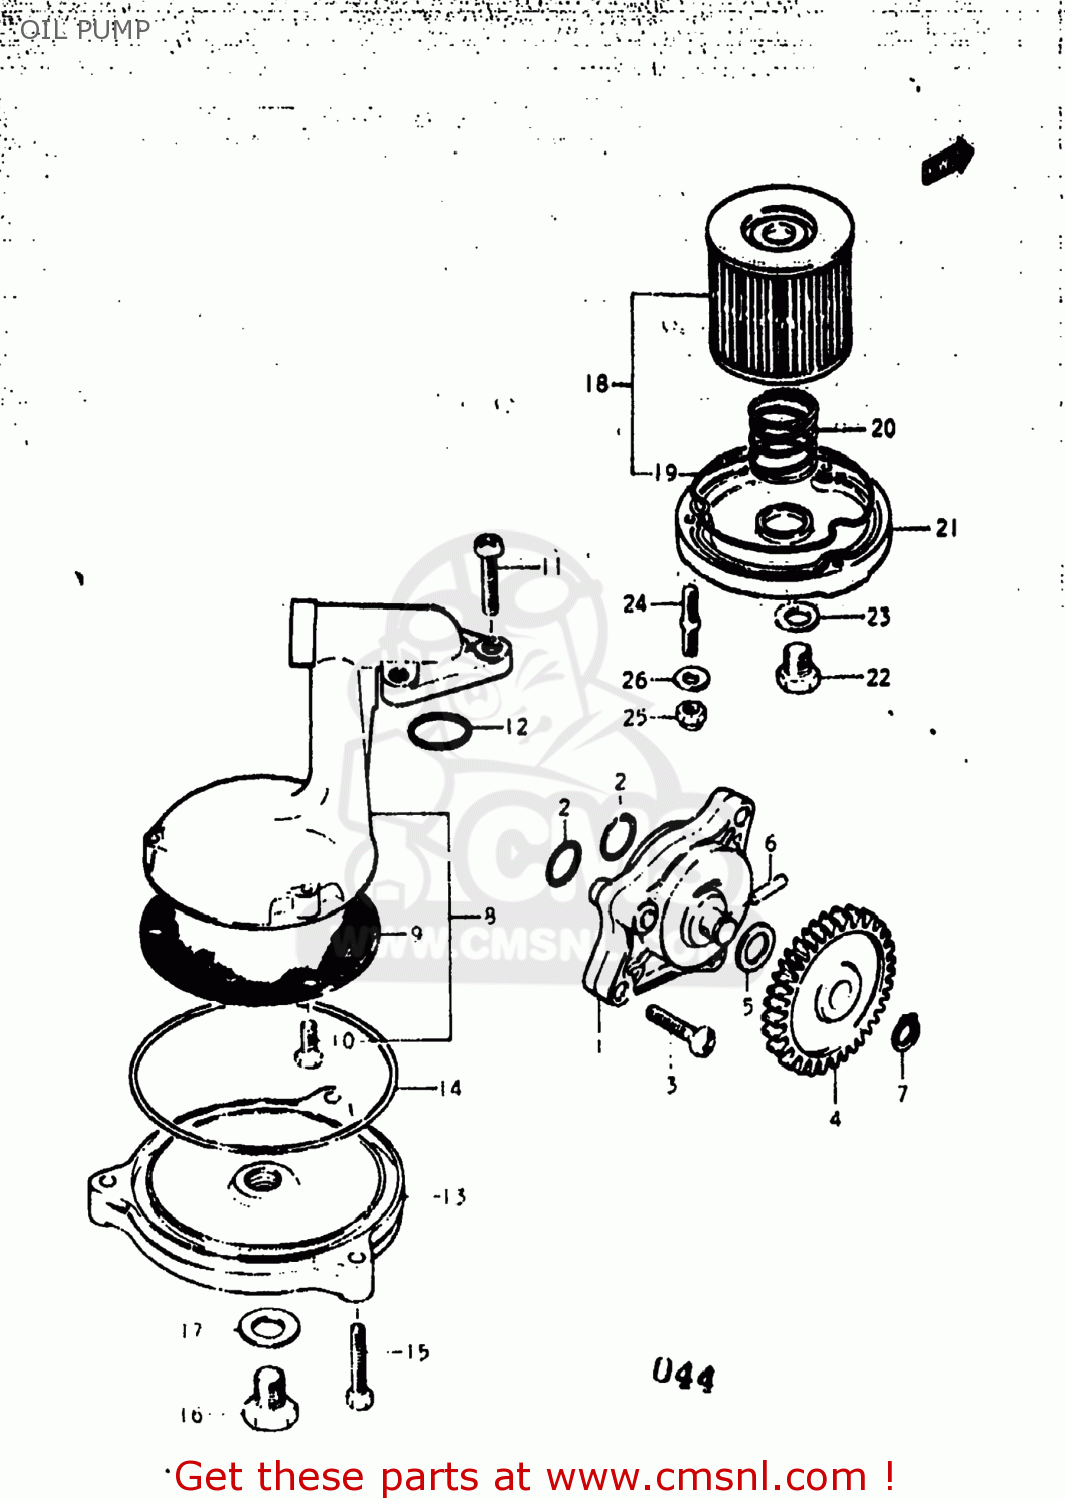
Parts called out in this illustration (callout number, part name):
1	PUMP ASSEMBLY,OIL
2	O RING(D:1.9,ID:13)
3	SCREW
4	GEAR,OIL PUMP DRIVEN
5	SHIM
6	PIN(4X15.8)
7	CIRCLIP
8	STRAINER,ENGINE OIL
9	NET
10	BOLT
11	SCREW
12	O RING(D:2.4,ID:15.8)
14	O RING(D:3.1,ID:83.4)
15	BOLT
16	PLUG
17	GASKET(14X19.2X2) (NAS)
18	ENGINE OIL FILTER SET
19	O RING,OIL FILTER CHAMBER CAP
20	SPRING
21	CAP,OIL FILTER
22	PLUG
23	GASKET(10.1X16X1) (NAS)
24	STUD 6X20
25	NUT
26	WASHER 6MM
